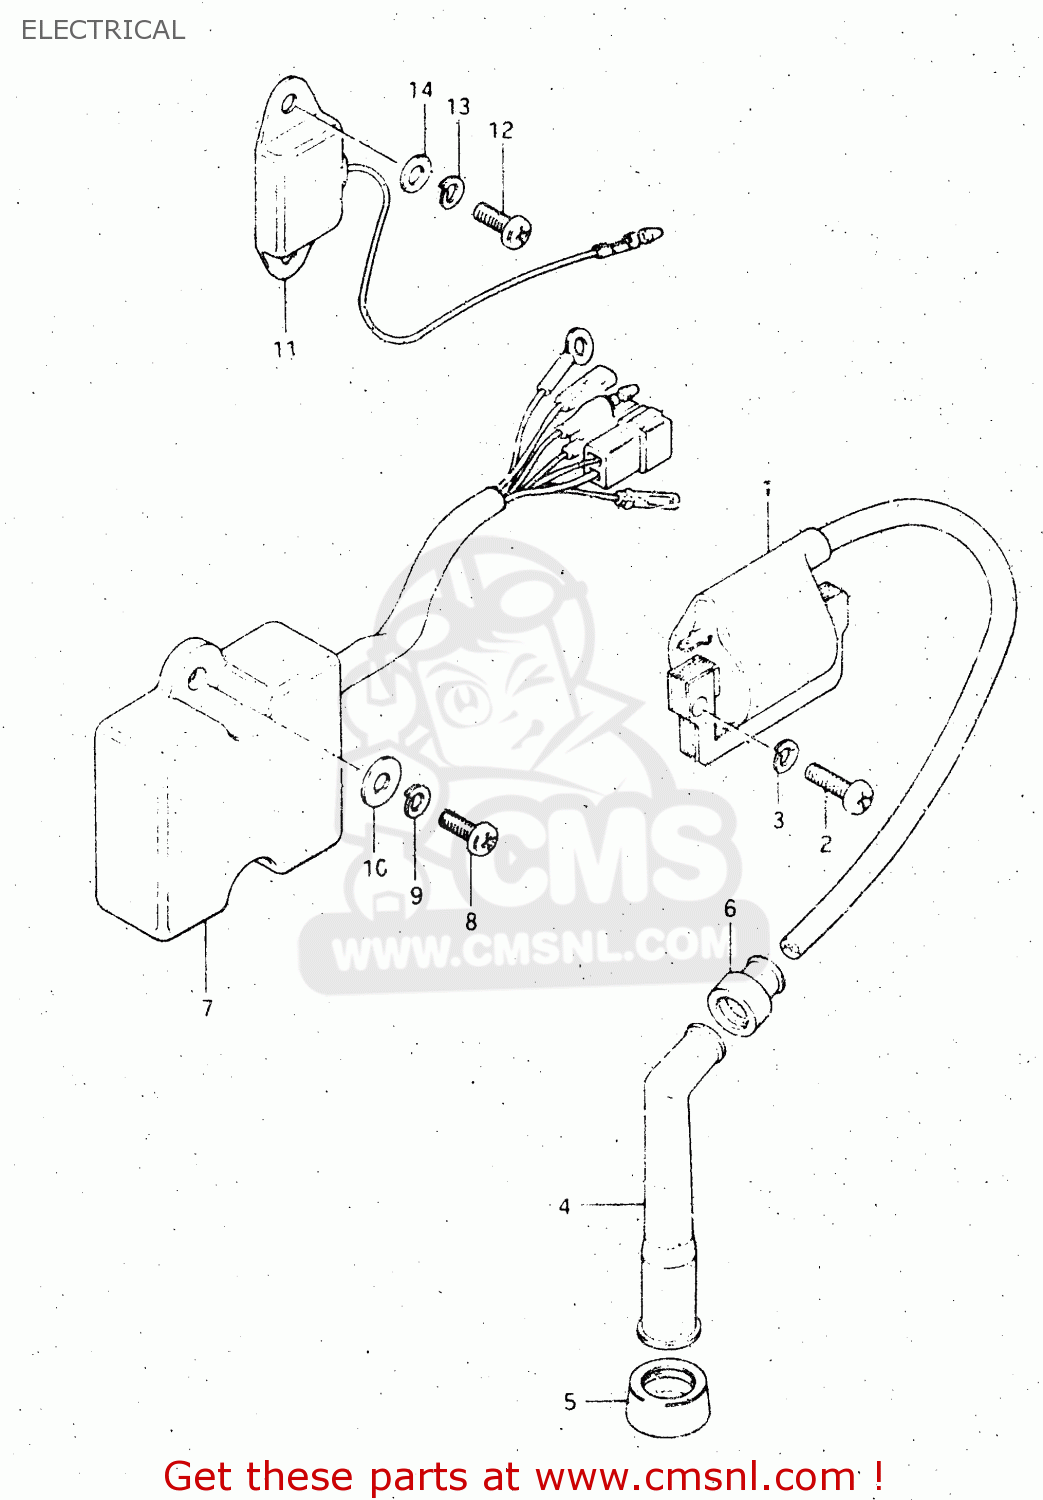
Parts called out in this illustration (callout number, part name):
1	COIL ASSEMBLY,IGNITION
2	SCREW
3	LOCK WASHER
4	CAP ASSY,SPARK PLUG
5	SEAL,SPARK PLUG
6	SEAL,SPARK PLU
7	CDI UNIT
8	SCREW
9	LOCK WASHER
10	WASHER (6.5X18X1.6)
11	REGULATOR ASSEMBLY,VOLTAGE
12	SCREW
13	LOCK WASHER
14	WASHER
